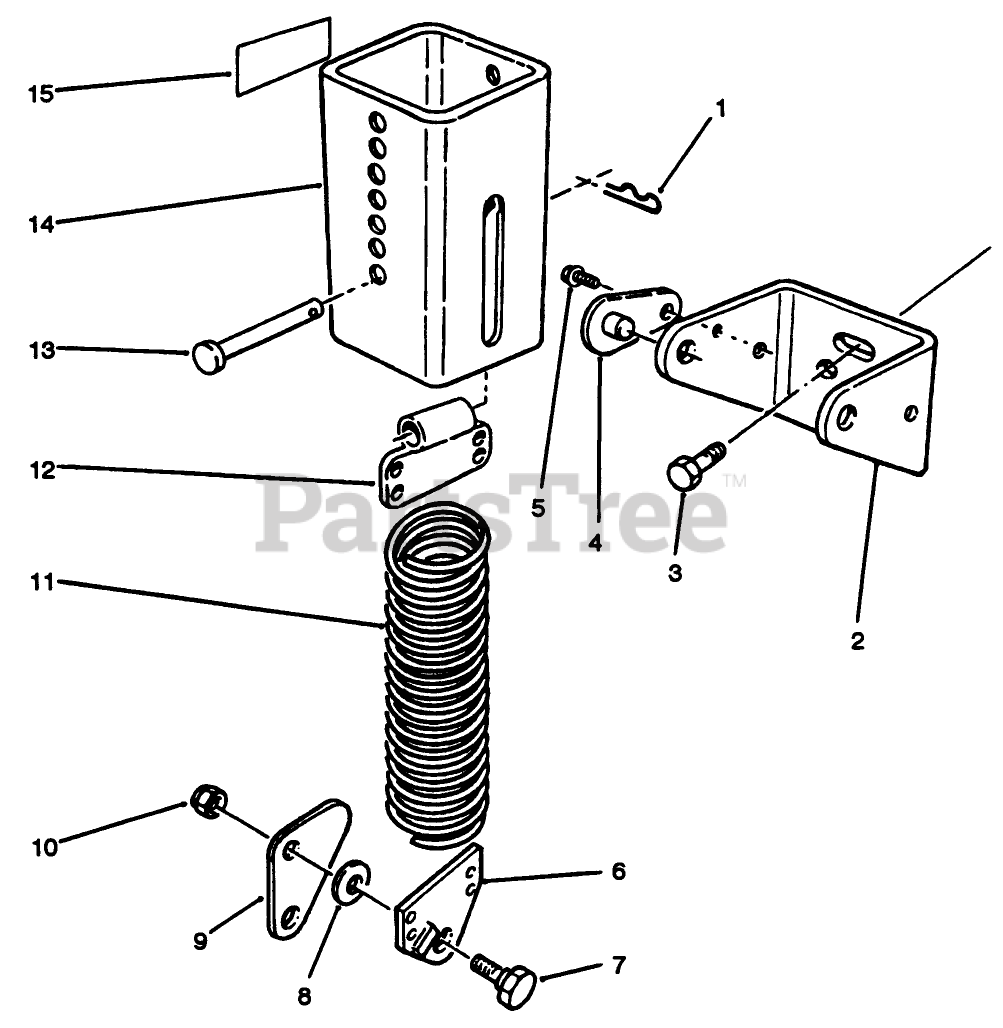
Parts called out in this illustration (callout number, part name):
1	PIN-HAIR
2	Bracket-Support
3	SCREW-HHF
4	PIN-LOCK
5	SCREW
6	End Spring
7	BOLT-SHOULDER
8	WASHER-FLAT
9	Link
10	NUT-LOCK, NI
11	Spring-Extension
12	End Spring
13	PIN-CLEVIS
14	Asm-Spring Cover
15	DECAL-WARNING
